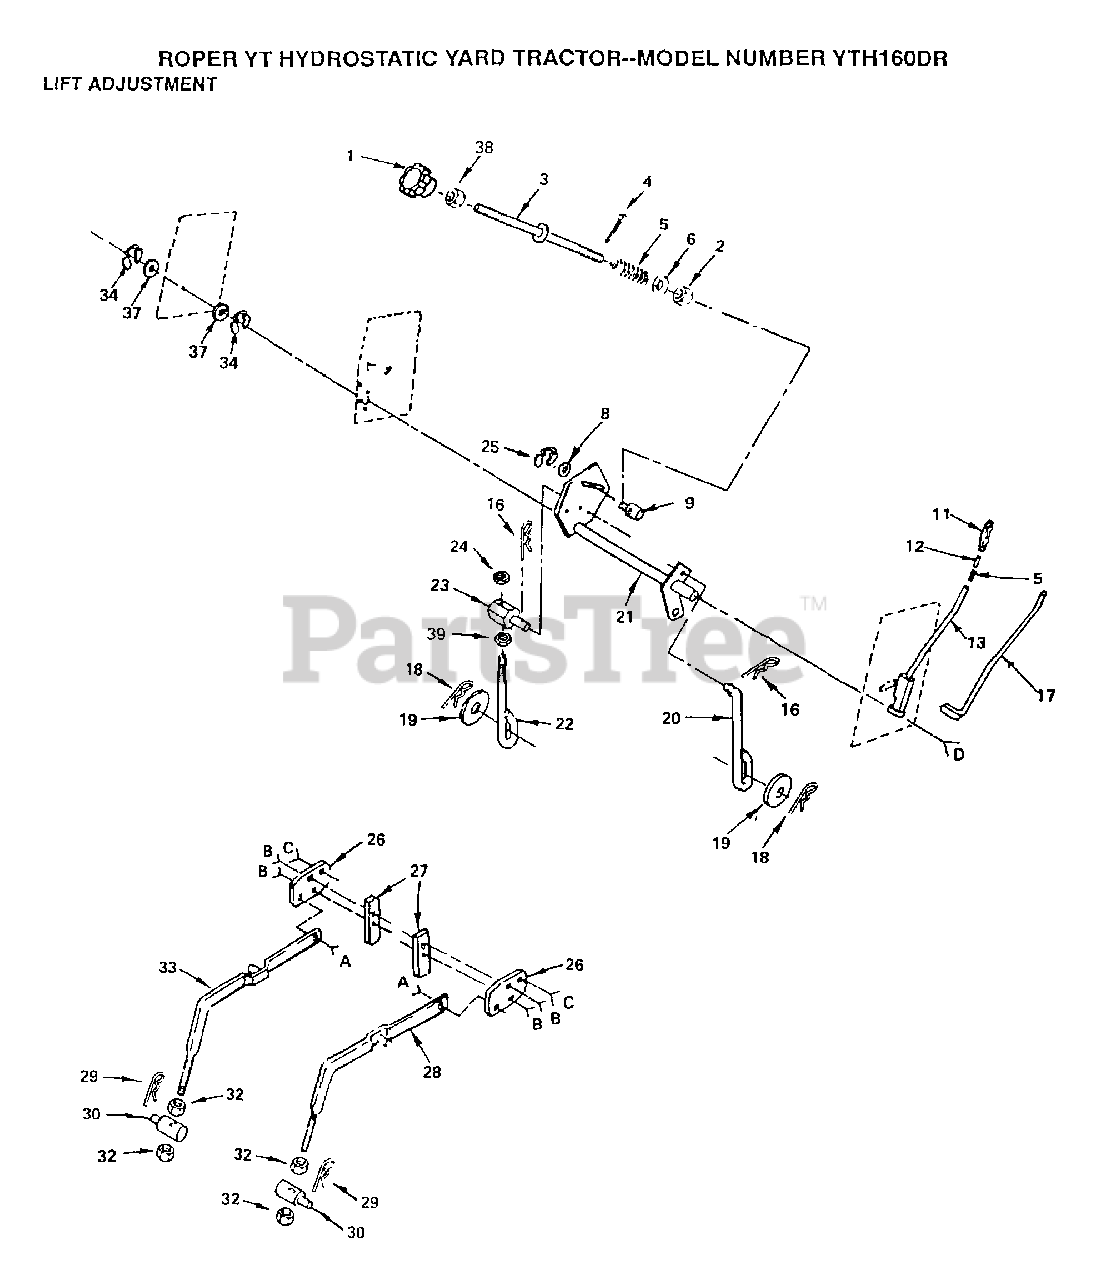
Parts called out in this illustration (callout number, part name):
1	HDLE ADJ LIFT
2	NUT T
3	ROD LIFT LT
5	SPRING T
6	WASHER
8	WASHER
9	TRUNION LT
11	GRIP
17	LEVER ROD LT
18	SPRING.RETAINER
20	LIFT LINK LT
22	PIVOT PIN T
25	KLIP RING
26	"BRACKET, SUSPE T"
27	UPSTOP
29	SPRING H
32	NUT
34	E-RING
37	WASHER
39	NUT
